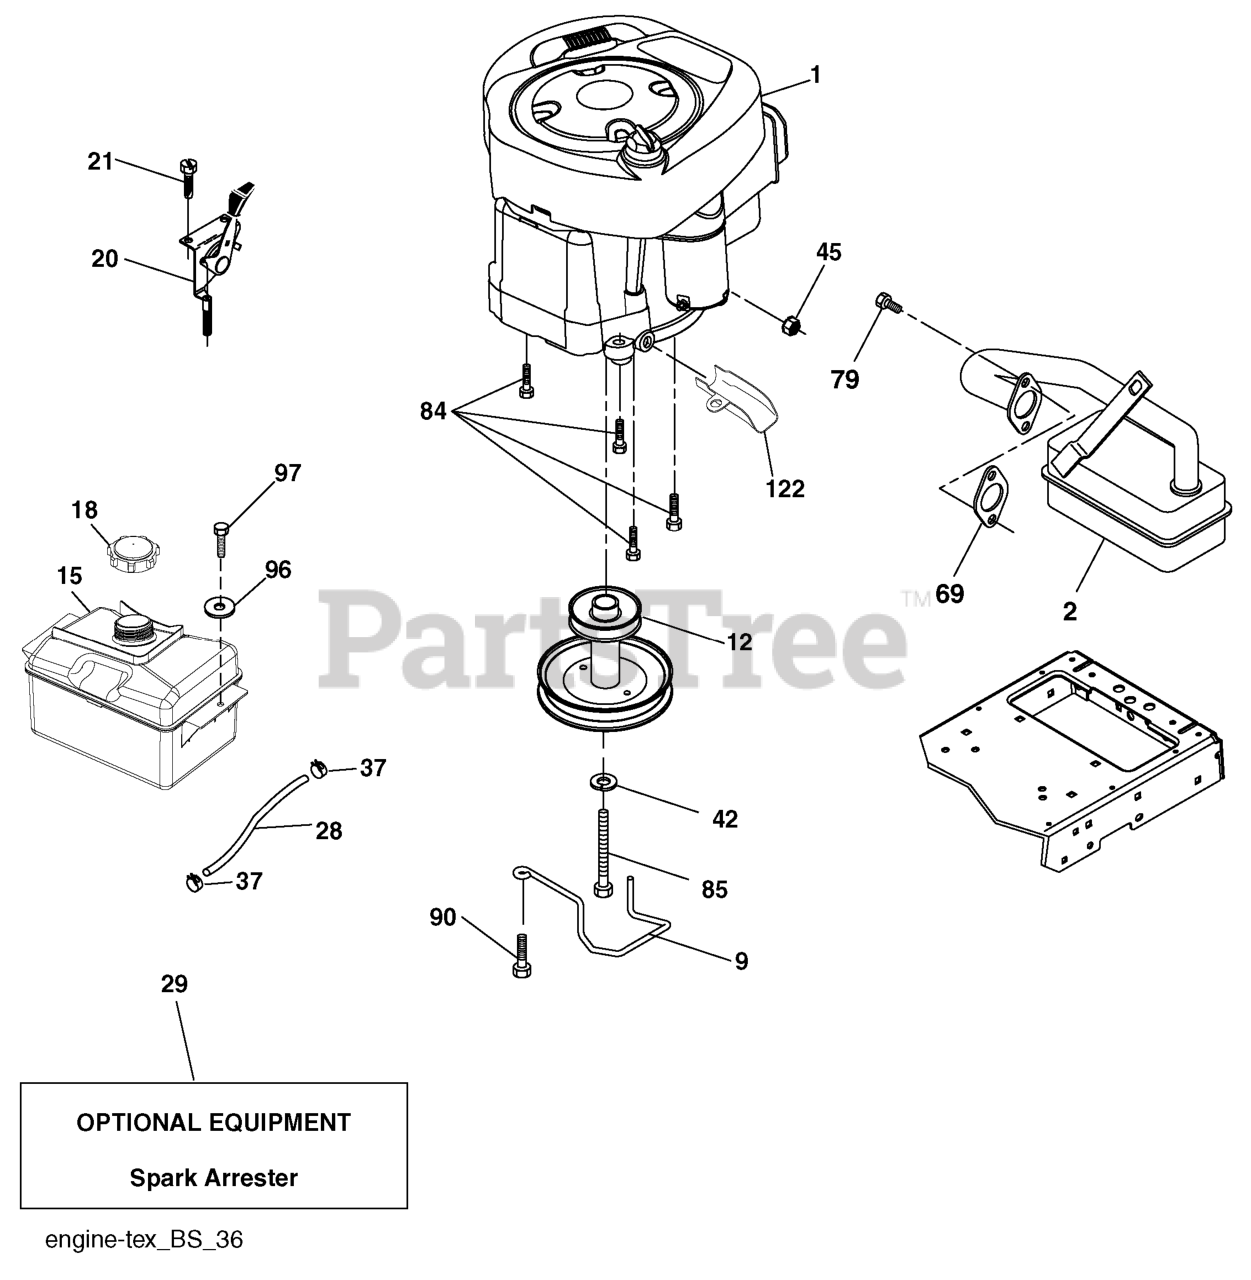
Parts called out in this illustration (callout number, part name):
2	MUFFLER.LT.BRIGGS.14HP.IC/OHV
9	KEEPER.BELT.ENGINE.4.2
12	PULLY ENGINE
15	RP TANK FUEL FRT 1.5 GAL
18	CAP ASM.FUEL.2.25"FR.
20	CONTROL.TH/CK.C.
21	SCREW.#10 X 0.750.BOS
28	LINE.FUEL.20"FRONT.EMI
29	KIT.SPARK ARRESTOR 794945 B&S
37	HOSE CLAMP
42	LOCKWASHER
45	NUT
69	REPL BY 532 27 22-93
79	SCREW.SOCKET HD.5/16-1
84	SCREW.3/8-16
85	BOLT HEX 7/16-20X4-1/4"
90	SCREW 3/8-16X1
96	WASHER
97	SCREW HEXWSHR 1/4-20X3/4
122	EXTENSION DRAIN OIL
